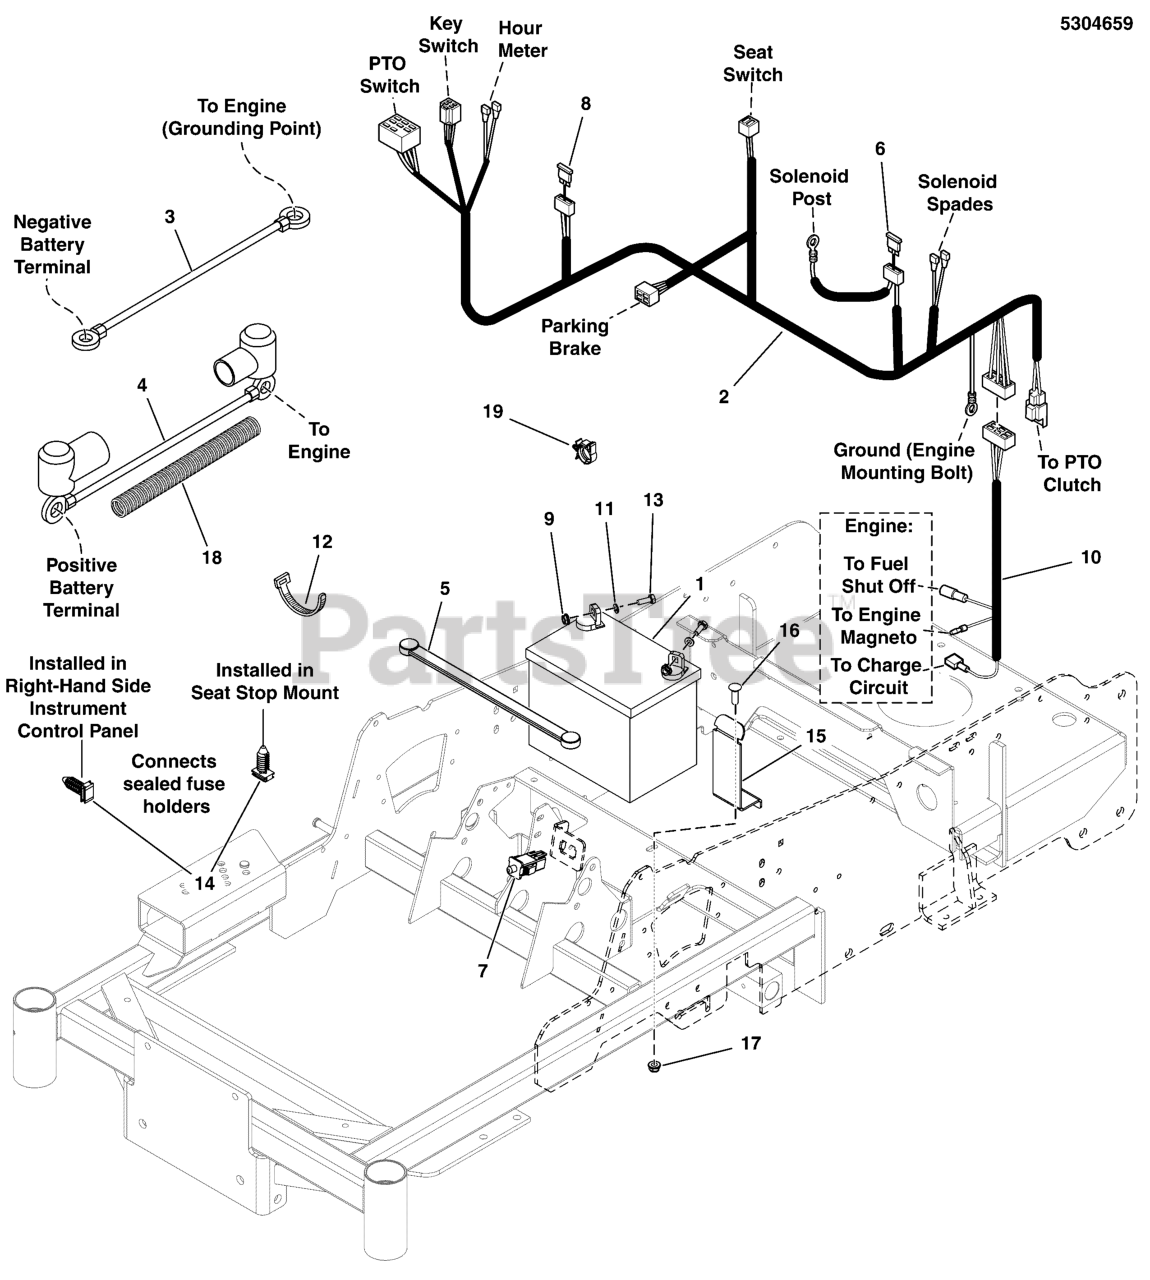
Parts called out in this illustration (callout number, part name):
1	BATTERY, 11U1L, 350 CCA
2	WIRE HARNESS, MAIN, PROSUMER, NO NEUTRAL
2	WIRE HARNESS, MAIN, SM, ZTR
2	HARNESS, Wiring, Small ZTR
3	BATTERY CABLE, NEG, 35, 1/4-5/16
4	BATTERY CABLE, POS, 30, 1/4-5/16
5	STRAP, BATTERY, 14 LONG, Rubber
6	FUSE, ATO-20 (20 AMP)(SV)
7	SWITCH, DP NO/NC SNAP-IN
8	FUSE, ATO-15 (15 AMP)(SV)
9	NUT, 1/4-20 HEX SERR. FLANGE
10	WIRE HARNESS, JUMPER, KAWI
11	WASHER, 1/4 SAE
12	TIE, SELF-LOCKING, 12"
13	BOLT, 1/4"-20 X 3/4" GD5 YZ
14	FIR TREE MOUNT, PACKARD
15	PLATE, HARNESS/BATTERY SUPPORT - BLK
16	BOLT, 5/16-18 X 1, CARRIAGE, GD5, CZ
17	NUT, 5/16-18 HEX NYLOCK FLANGE NUT
18	WIRE LOOM, 3/8 ID X 26 IN
19	ROSEBUD LOOM CLIP
